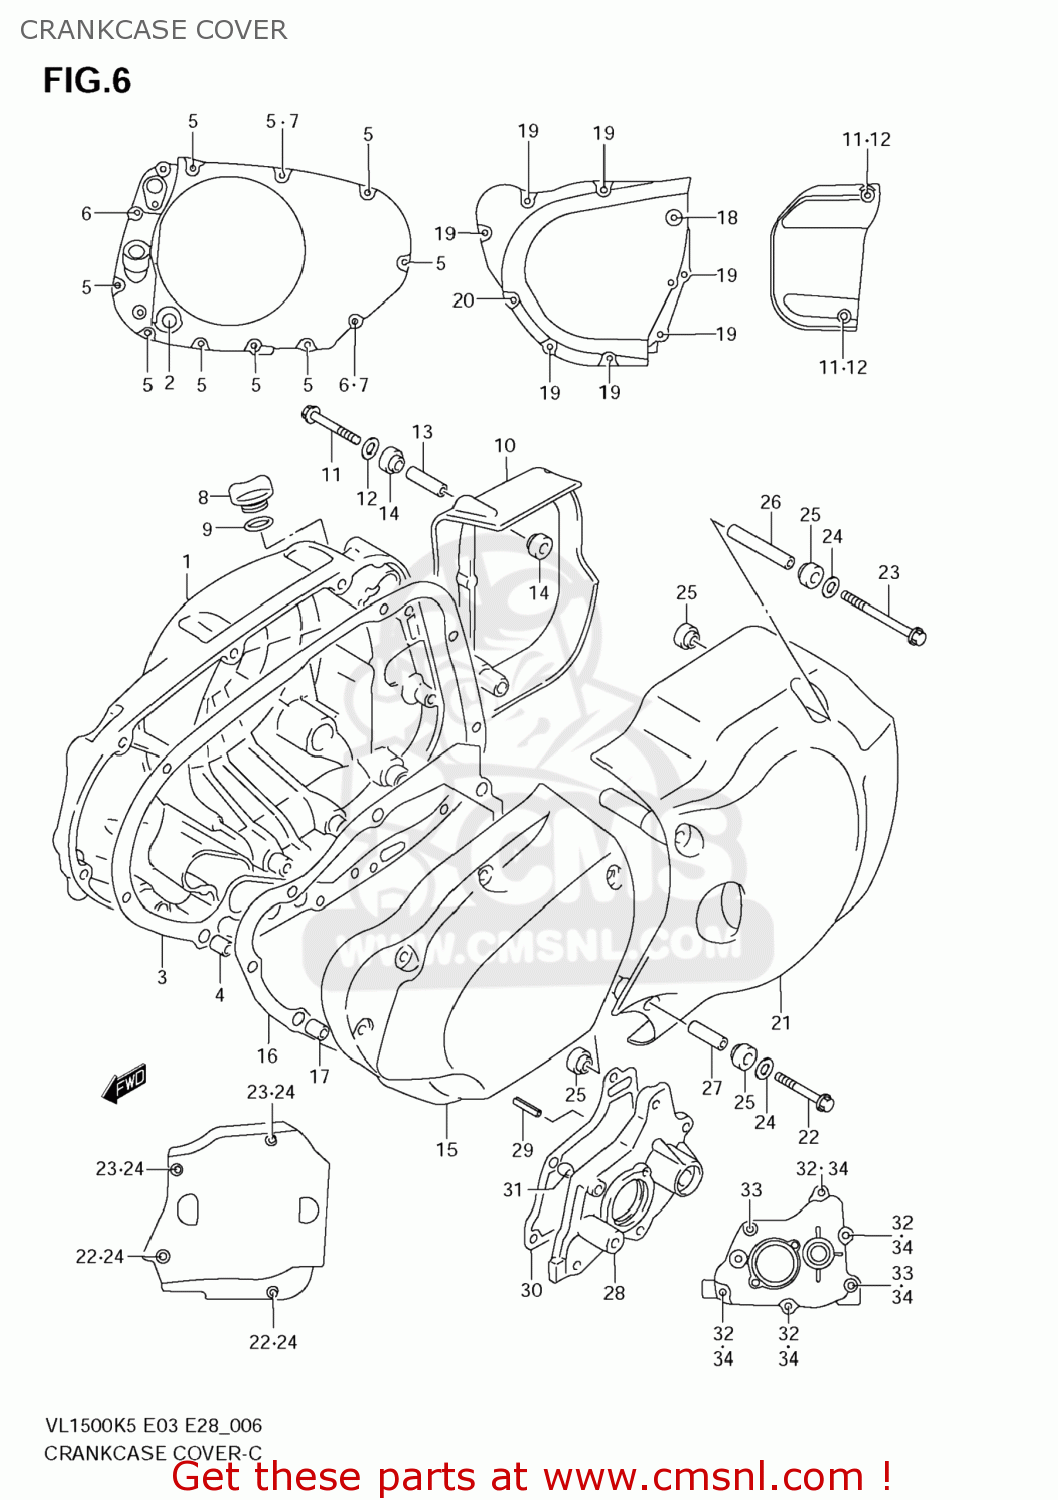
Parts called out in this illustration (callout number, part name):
1	COVER,CLUTCH
2	LENS,OIL LEVEL CHECK
3	GASKET,CLUTCH COVER (NAS)
4	PIN
5	BOLT(6X30)
6	BOLT(6X40)
7	GASKET(5.8X13X1.2) (NAS)
8	PLUG,ENGINE OIL FILLER
9	O RING(D:3.1,ID:16.8)
10	COVER,CLUTCH RR
11	BOLT(6X45)
12	WASHER(6.5X14X1.6)
13	SPACER(6.5X9X31.5)
14	WASHER(8.7X16X5)
15	COVER,GENERATOR
16	GASKET,GENERATOR COVER (NAS)
17	PIN(8.4X11X20)
18	BOLT(6X95)
19	BOLT(6X35)
20	BOLT(6X45)
21	COVER,SECONDARY DRIVE UNIT
22	BOLT(6X40)
23	BOLT(6X70)
24	WASHER(6.5X14X1.6)
25	WASHER(8.7X16X5)
26	SPACER(6.1X9X55.9)
27	SPACER(6.5X9X26)
28	COVER,GEAR SHIFT
29	PIN,SPRING(3.5X16)
30	GASKET,GEAR SHIFT COVER (NAS)
31	PIN
32	BOLT
33	BOLT
34	GASKET(5.8X13X1.2) (NAS)
